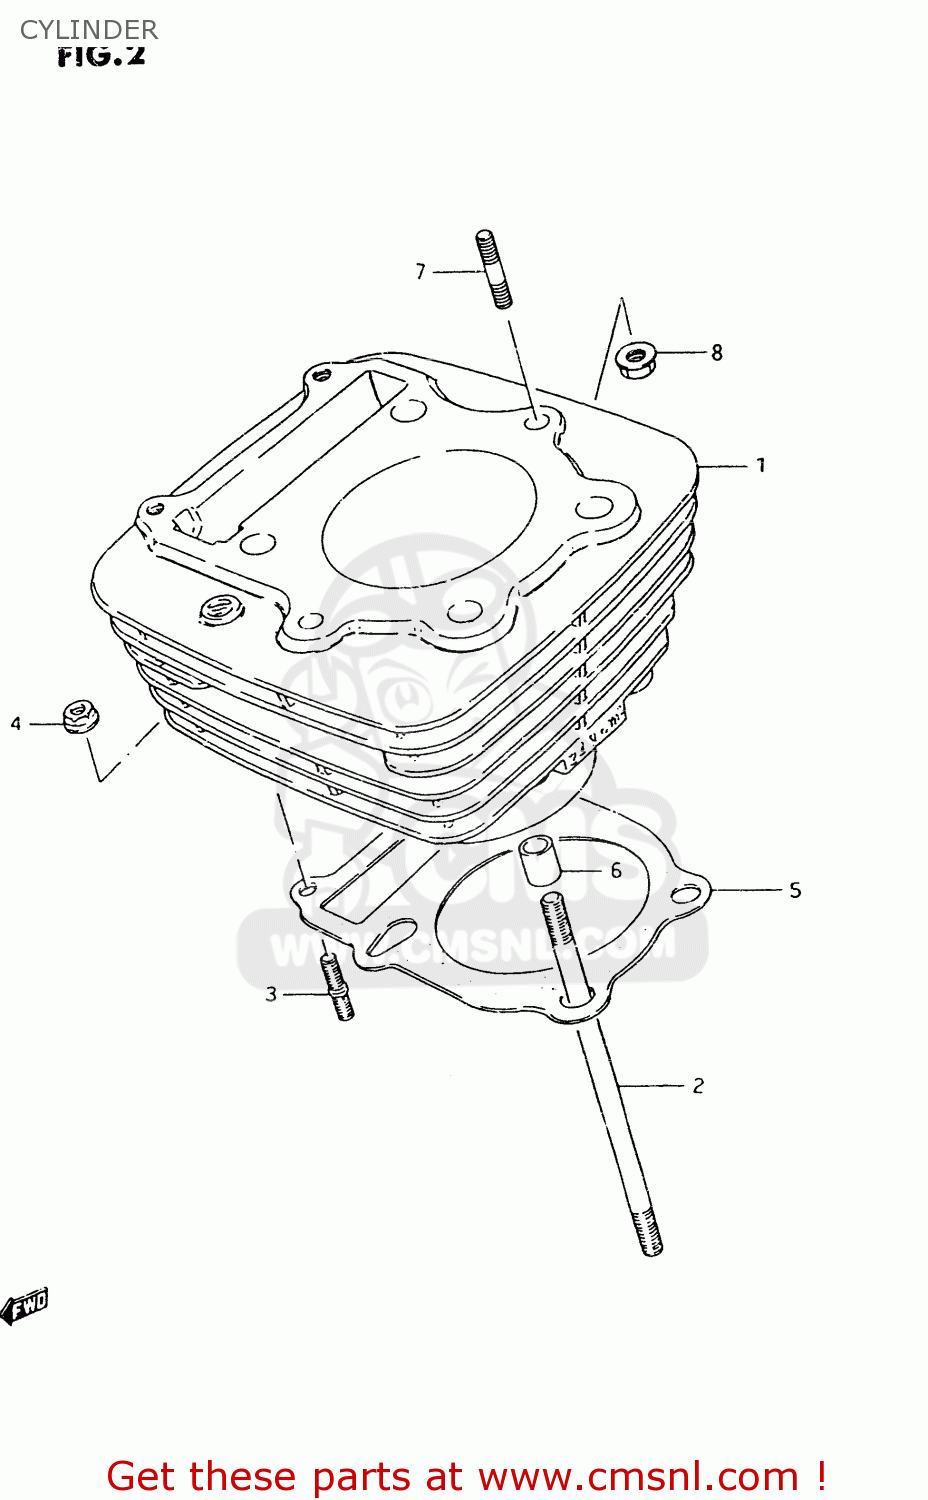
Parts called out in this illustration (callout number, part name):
1	CYLINDER
2	BOLT,STUD
3	STUD 6X20
4	NUT
5	GASKET,CYLINDER (NAS)
6	PIN
7	BOLT,STUD
8	NUT
